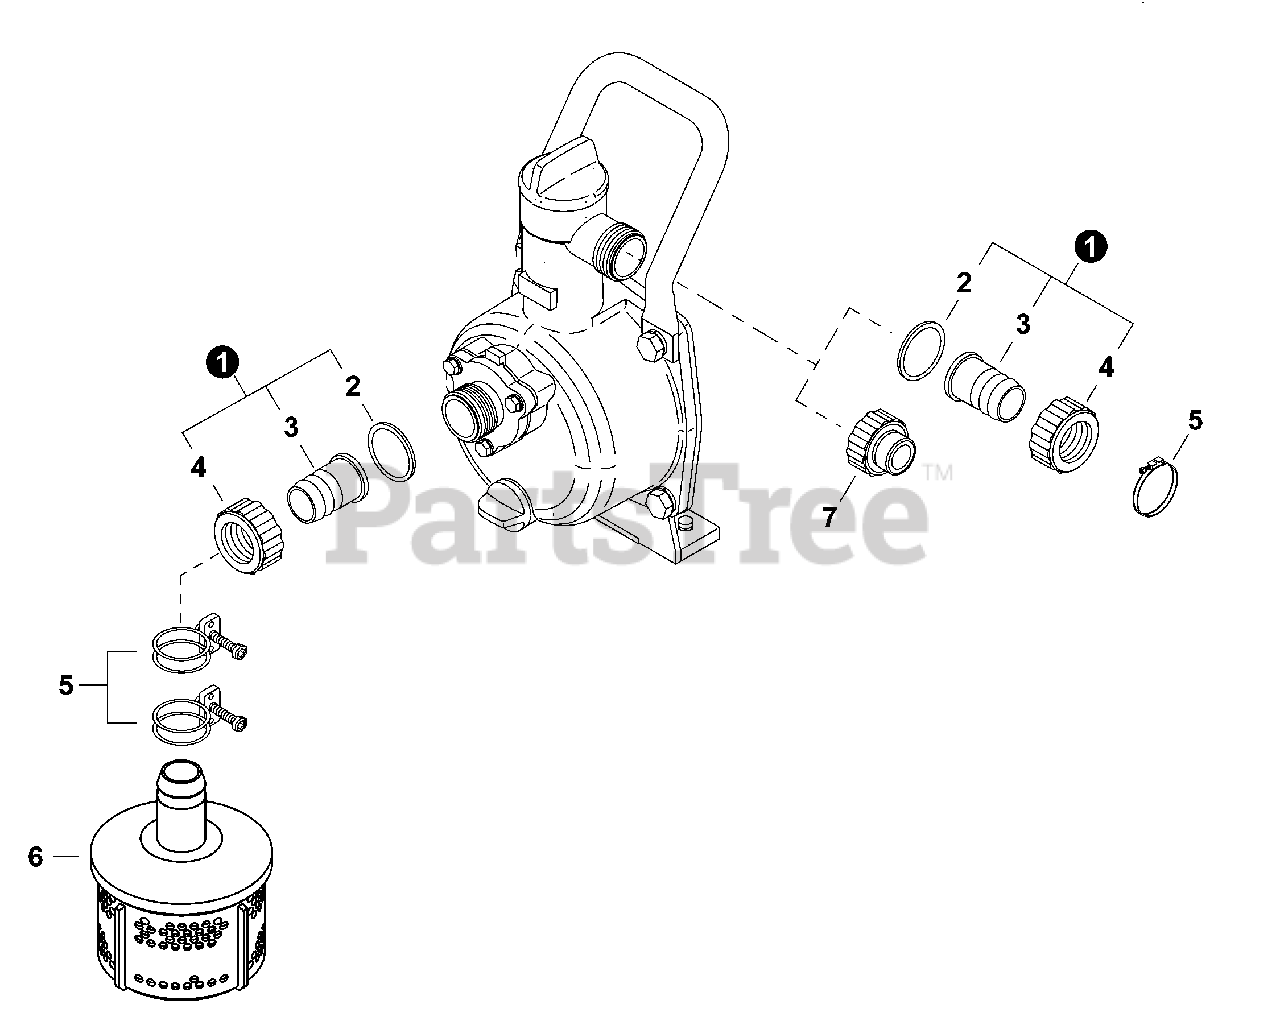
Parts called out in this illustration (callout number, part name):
1	COUPLING KIT, HOSE 25 MM
3	COUPLING, HOSE
4	NUT, RING
5	CLAMP, HOSE Ø32
6	STRAINER
7	ADAPTOR, HOSE
